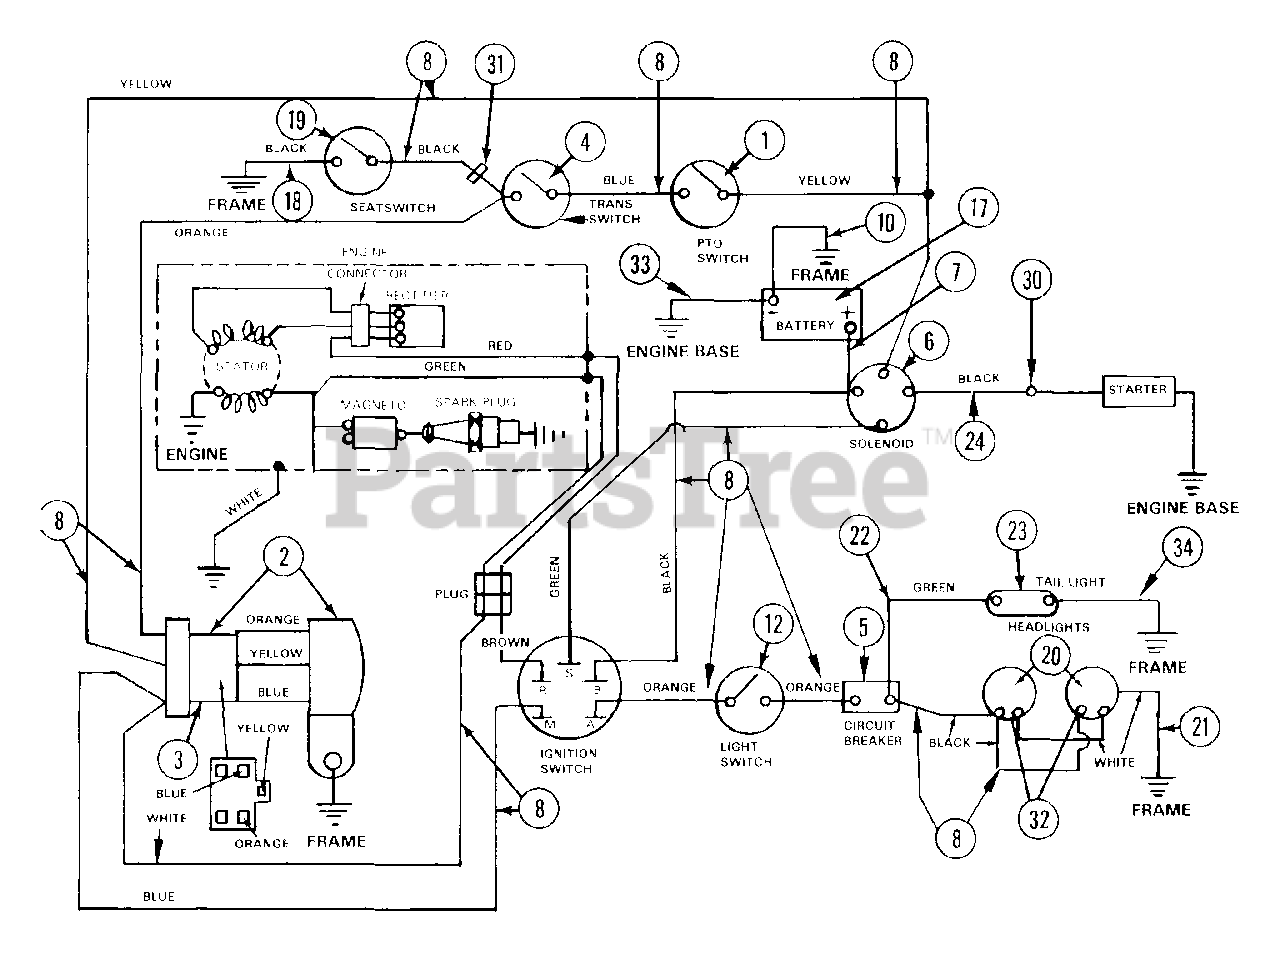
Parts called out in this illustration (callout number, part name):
1	SWITCH INTERLOCK
2	MODULE
3	CONNECTOR
4	SWITCH-NEUTRAL START N.O.
5	CIRCUIT BREAKER
6	SOLENOID
7	GROUND CABLE
8	WIRE HARNESS
10	GROUND CABLE
11	IGNITION SWITCH
12	LIGHT SWITCH
17	BATTERY
18	GROUND WIRE
19	SWITCH SEAT
20	HEAD LIGHT
22	TAIL LIGHT WIRE
23	TAIL LIGHT
24	GROUND CABLE
30	TIE DOWN
31	MUFFLER
32	CLAMP LOOP
33	GROUND CABLE .31X22.00X.31
34	GROUND WIRE
